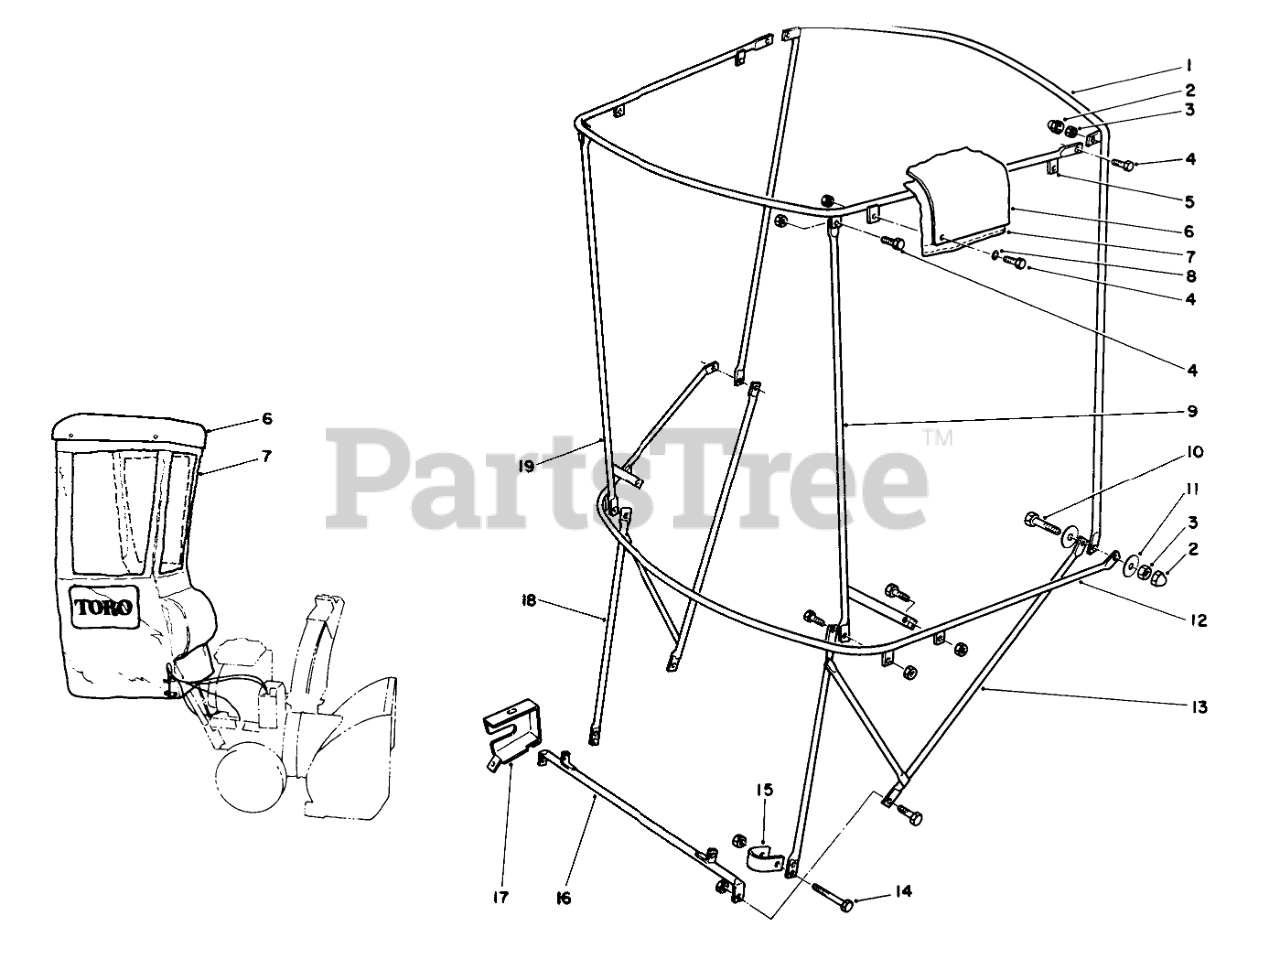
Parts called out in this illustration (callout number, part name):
1	VERTICAL BOW
2	CAPLUG
3	NUT-HEX, SIDE DEFORM
4	SCREW-HH
5	FRAME - TOP
6	Top-Plastic
7	Cover-Vinyl
8	WASHER-FLAT
9	CORNER POST - LH
10	SCREW-HH
11	WASHER-FLAT
12	HORIZONTAL BOW
13	Bracket-LH
14	SCREW-HH
15	CLAMP
16	Bracket-Base
17	COVER-LOCK, LEVER
18	BRACKET-RH
19	CORNER POST - RH
